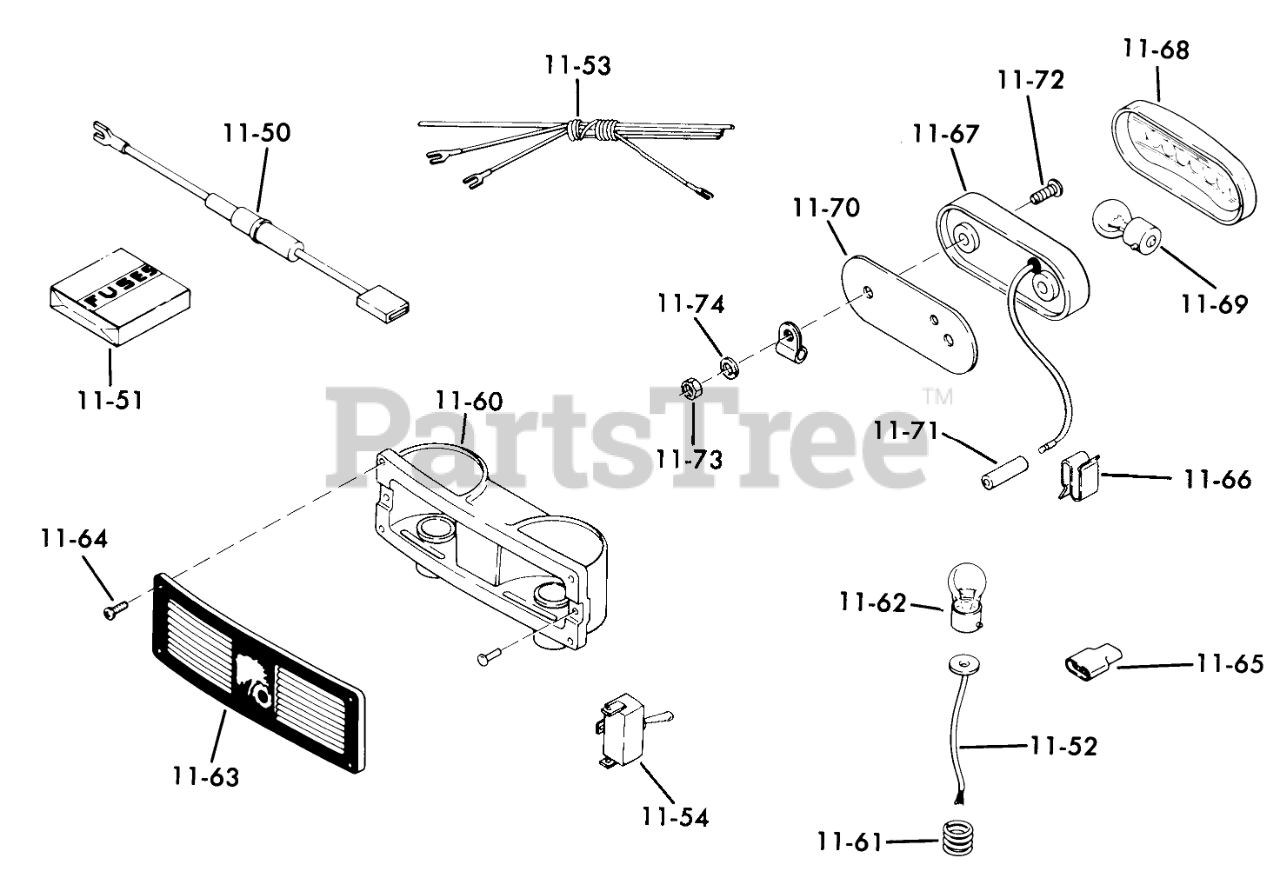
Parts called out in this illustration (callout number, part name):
11-50	ASSY FUSED CONNECTOR
11-52	WIRE ASSY
11-53	Wire Harness-Lights
11-54	SWITCH-LIGHTS
11-60	ASSY REFLECTOR HOUSI
11-61	SPRING
11-62	BULB
11-63	Lens
11-64	Pan HD Swage
11-65	CONNECTOR 3 WIRE
11-66	SPEED CLIP
11-67	Base
11-68	Lens
11-69	Bulb
11-70	Mounting Pad
11-71	CONNECTOR 2 WIRE
11-72	Screw
11-73	Nut
11-74	Lockwasher
